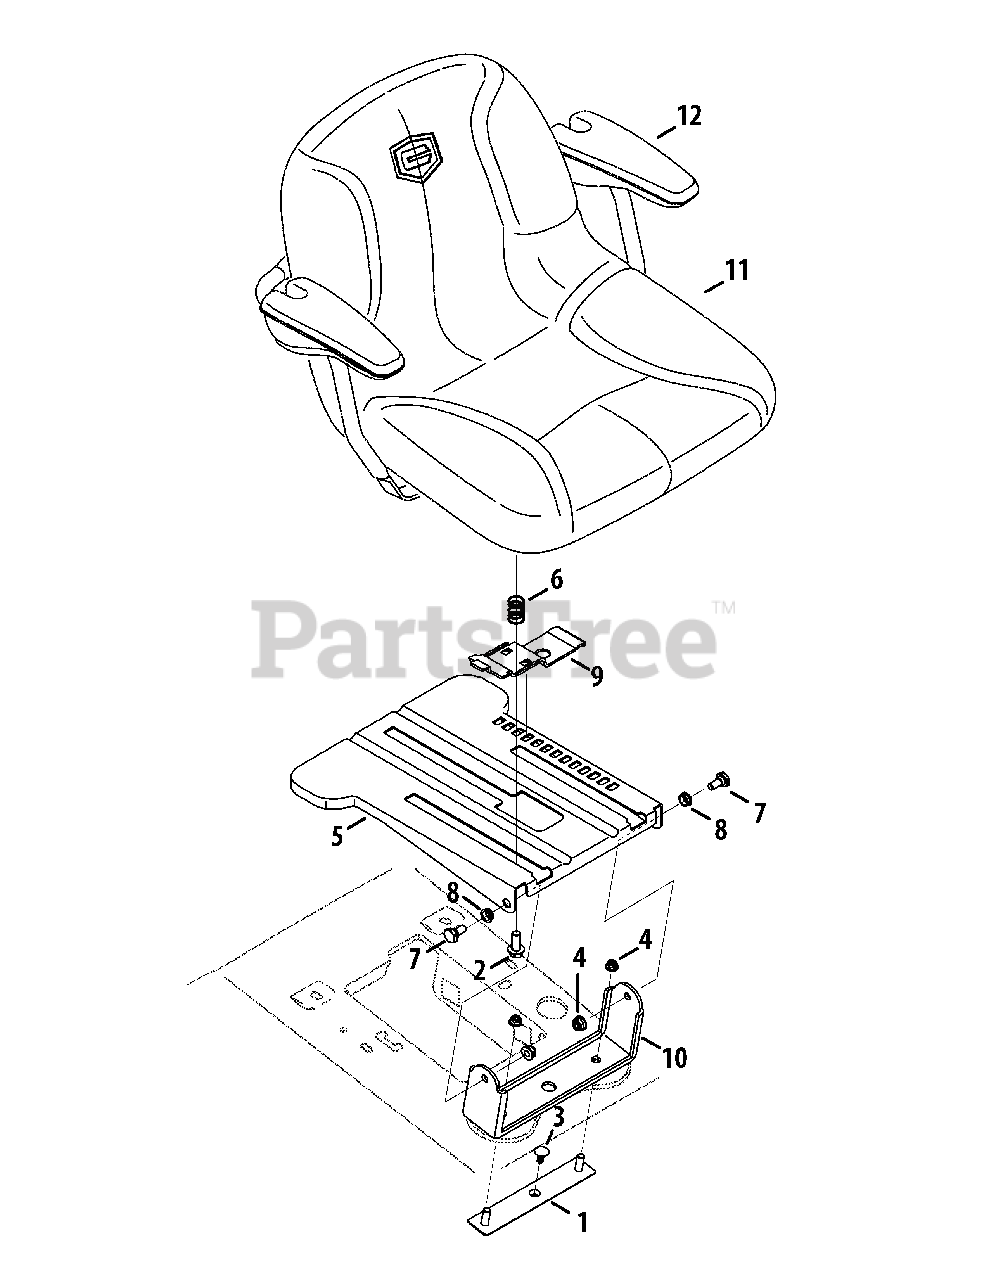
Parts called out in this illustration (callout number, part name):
1	Seat Pivot Plate Assembly
2	Hex Flange Screw, 3/8/16, .875, Gr5
3	Ratchet Clip
4	Nut, Flange Lock, 5/16-18, Grf
5	Bracket, Mounting, Seat
6	Compression Spring, .68 x 1.065 x .055
7	Shoulder Screw, .435 x .178, 5/16 x .56
8	Flange Bearing, .4385 ID
9	Seat Lever
10	Pivot Bracket, Tall
11	Seat
12	Arm Rest Kit
